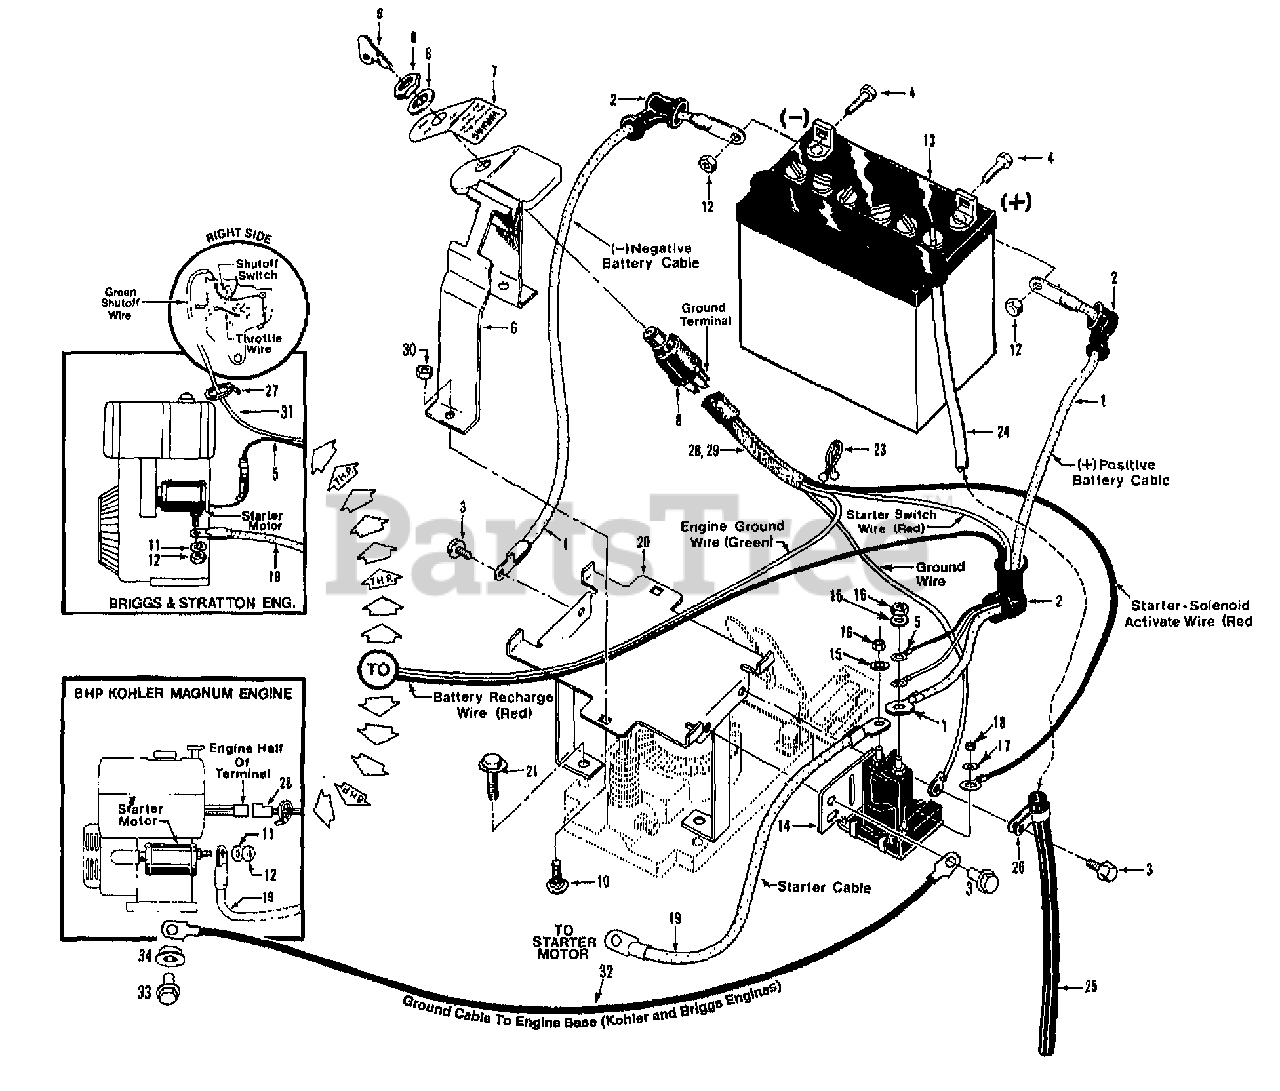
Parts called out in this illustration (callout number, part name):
1	CABLE-BATTERY 10"
2	BOOT-BATTERY CABLE
3	SCR-HWH 1/4-20 X .5 STH
4	SCR-HH 1/4-20X.625
5	WIRE-RECHARGE 5&7 BRIGGS
6	KEYSWITCH W/DECAL HORSE
7	DECAL-IGNITION TILLERS
8	ASSM-KEYSWITCH ELEC TLR
9	KEYS-IGN T/BLAZER 1 PAIR
10	SCR-CARR 1/4-20X1.25
11	WASHER-LK .25 ZP
12	NUT-HEX 1/4-20 ZP
13	BATTERY-12 VOLT HORSE
14	SOLENOID
15	WASHER-LK .312 ZP
16	NUT-HEX 5/16-24
17	WASHER-EXTERNAL TOOTH 1
18	NUT-HH M10-32X.125
19	CABLE-BATTERY 12"
20	BRKT-BATTERY OPC PNT
21	SCR-HFLK 3/8-16X1.50
23	TIE-TWIST LOCK
24	TUBE-VENT BATTERY/HSE
25	TUBING-RUBBER
26	CLAMP
27	TIE-RED
28	KIT-WIRE HARNESS ASSM
29	ASSM-WIRE HARNESS
30	NUT-HF/LK 1/4-20 ZP
31	ASSM-WIRE SWITCH/GROUND
31	CABLE-BATTERY 15"
32	CABLE-BATTERY 15"
33	SCR-HFLK 5/16-18X1.00 ZP
34	NUT-HFLK 5/16-18 ZP
